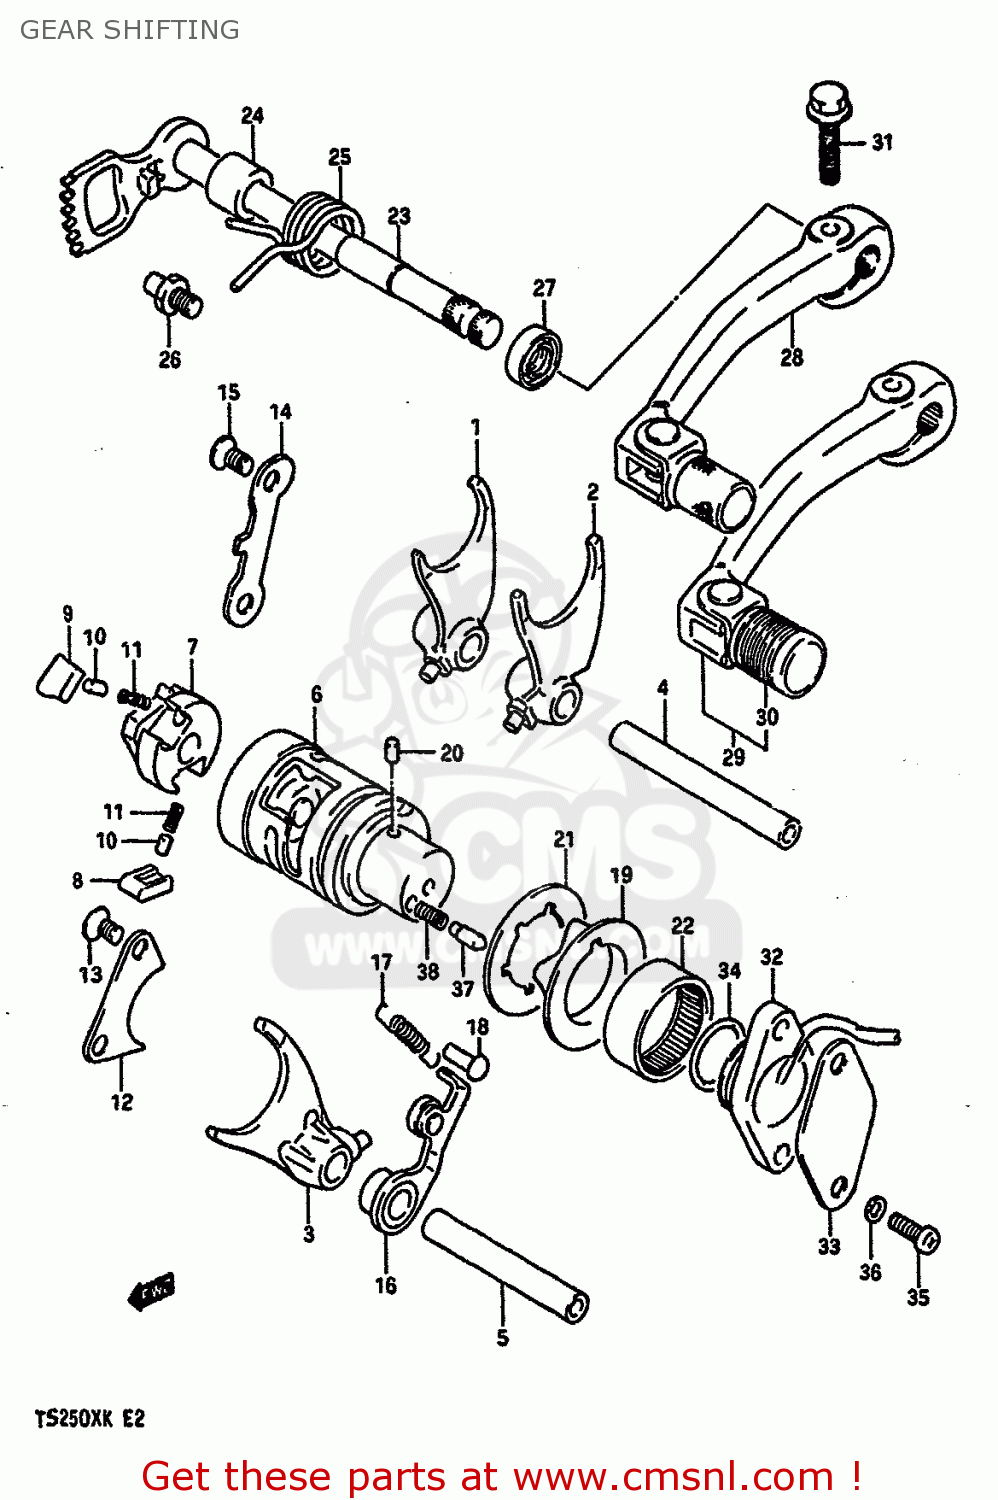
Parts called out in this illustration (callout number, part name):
1	FORK,GEAR SHIFT NO.1
2	FORK,GEAR SHIFT NO.2
3	FORK,GEAR SHIFT NO.3
4	SHAFT,GEAR SHIFT FORK
5	SHAFT,FORK NO.2 (L:70)
6	CAM,GEAR SHIFT
7	GEAR,GEARSHIFT CAM DRIVE
8	PAWL,GEAR SHIFT NO.1
9	PAWL,GEAR SHIFT NO.2
10	PIN(5X8)
11	SPRING
12	LIFTER,GEAR SHIFT PAWL
13	SCREW
14	GUIDE,GEAR SHIFT CAM
15	SCREW
16	STOPPER,GEAR SHIFTING CAM
17	SPRING
18	RIVET
19	PLATE,GEAR SHIFT CAM STOPPER
20	PIN
21	WASHER,LOCK
22	BEARING(25X32X12)
23	SHAFT,GEAR SHIFT
24	SPACER(12X20X15.3)
25	SPRING
26	STOPPER,GEAR SHIFT CAM
27	OIL SEAL
28	LEVER ASSY,GEAR SHIFTING
29	LEVER ASSY,GEAR SHIFTING
30	RUBBER,GEAR SHIFT PEDAL
31	BOLT
32	BODY,SWITCH
33	PROTECTOR,SWITCH
34	O RING(D:2.5,ID:21)
35	SCREW
36	WASHER,LOCK
37	PIN(5X15.5)
38	SPRING
